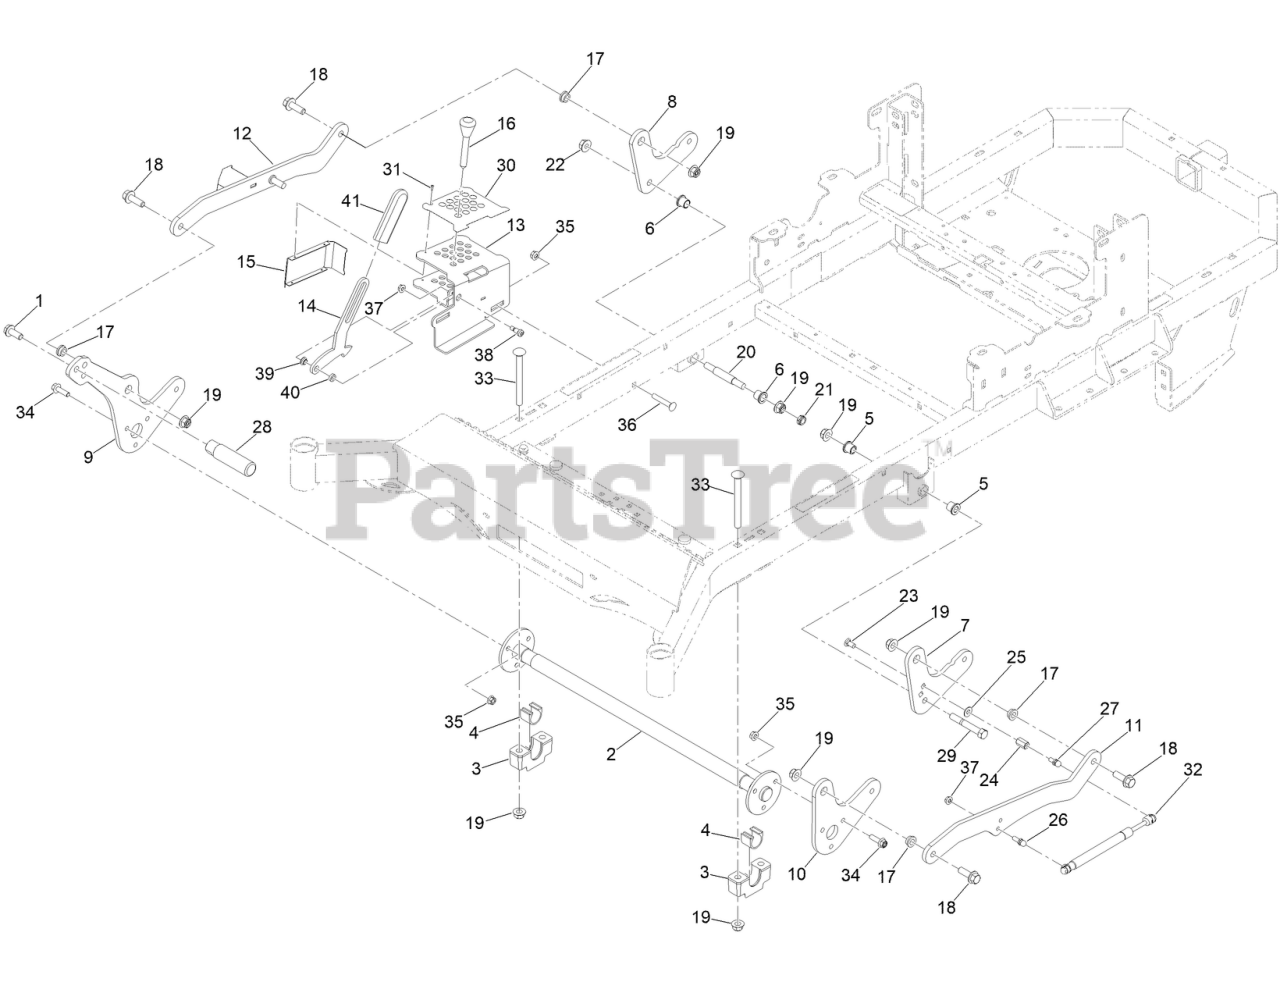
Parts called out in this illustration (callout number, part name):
1	1/2-13X1.25IN HEX FLANGE BOLT (GR.8) YZ
2	DECKLIFT ASM-FRONT
3	SUPPORT-BEARING HOUSING
4	BEARING-CROSS SHAFT, FRONT
5	BUSHING-FLANGE
6	BUSHING-FLANGE
7	(RZ REAR HOC HANGER)
8	ARM-DECKLIFT REAR (3/8")
9	LEVER-LIFT
10	PLATE-DECKLIFT, ARM LH
11	LINK-HOC(LEFT SIDE)
12	LINK ASM-HOC(RIGHT SIDE WELDED)
13	BRACKET-HOC ASM [GRAY]
14	PLATE-TRANSPORT LOCK
15	COVER-HOC
16	MAGNETIC PIN FOR STAND ON MWR
17	1/2IN ID X 3/4IN OD X 3/8IN FLANGE BUSH
18	SCREW-HHF
19	1/2-13 HEX FLANGE 2-WAY REV CNTR L/NYZ
20	RR DECK HEIGHT BOLT (MACHINED)
21	NUT-HEX
22	NUT-HHF
23	3/8 X 3/4IN GR 8 CARR BOLT ZINC
24	HEX COUPLING NUT - REDUCER (3/8" TO 5/16
25	WASHER-FLAT
26	5/16-18X1.286 DAMPER BALL STUD (.562 TL)
27	5/16-18X1.286 DAMPER BALL STUD (.562 TL)
29	1/2-13 X 3-1/2 HEX C/S GR 5 ZINC YELLOW
30	DECAL-HEIGHT OF CUT
31	RIVET
32	RZ DECK ASSIST GAS SPRING
33	SCREW-CARR
34	SCREW-HHF
36	SCREW-CARR
38	3/8 X 1/2 SOCKET SHOULDER BOLT YZ
39	BUSHING-FLANGE
40	WASHER-PLAIN
41	STAND UP MWR BRAKE ARM GRIP
